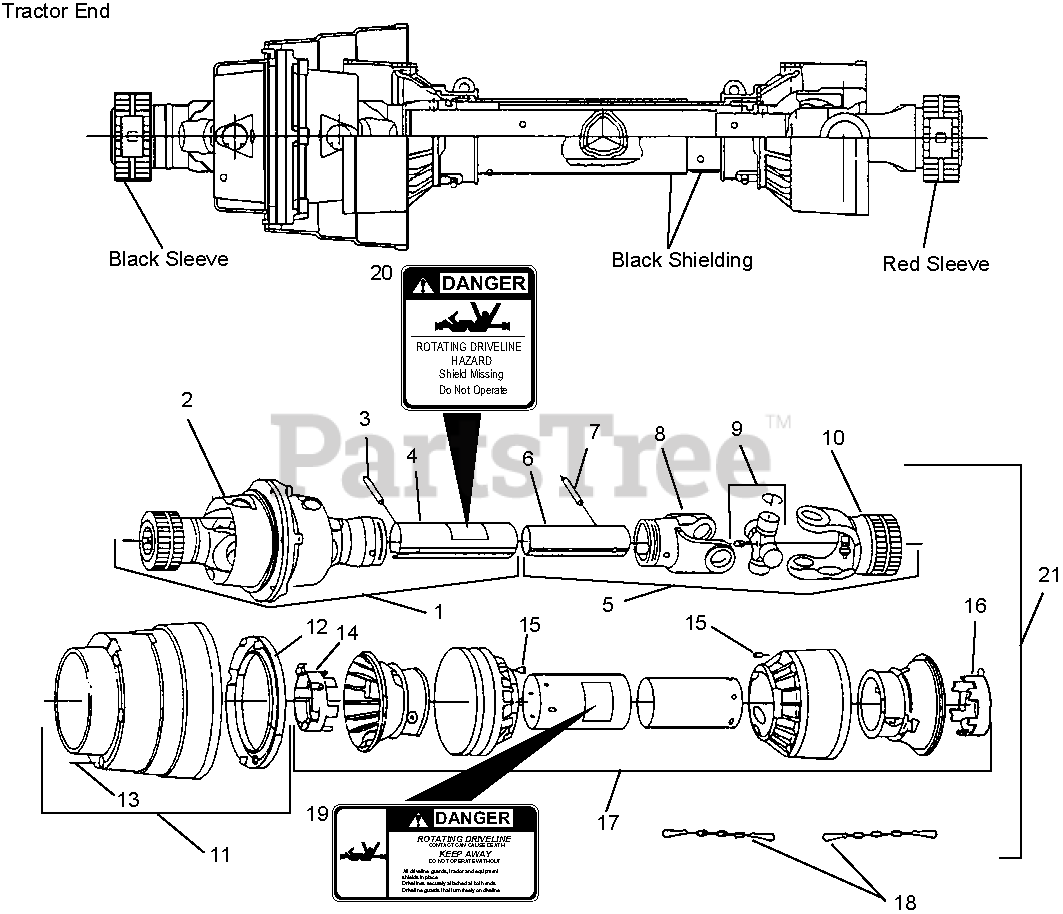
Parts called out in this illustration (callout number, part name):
2	Assembly, Constant Velocity Joint (Tractor End)
3	Pin, Roll 8 mm x 60 mm
4	Tube, Outer
6	Tube, Inner
7	Roll Pin 8 mm x 55 mm
8	Yoke, Inner Tube
9	Kit, Cross and Bearing
10	Assembly, Yoke (Implement End)
11	Shield, Wide Angle
12	Bearing, Soft Cone
13	Screw, Self-Tapping #6
14	Tube, Bearing Outer
15	Pin, Lock
16	Tube, Bearing Inner
17	Shield, Safety
18	Chain, Safety
19	Decal, Danger
20	Decal, Danger
21	Assembly, Driveline
